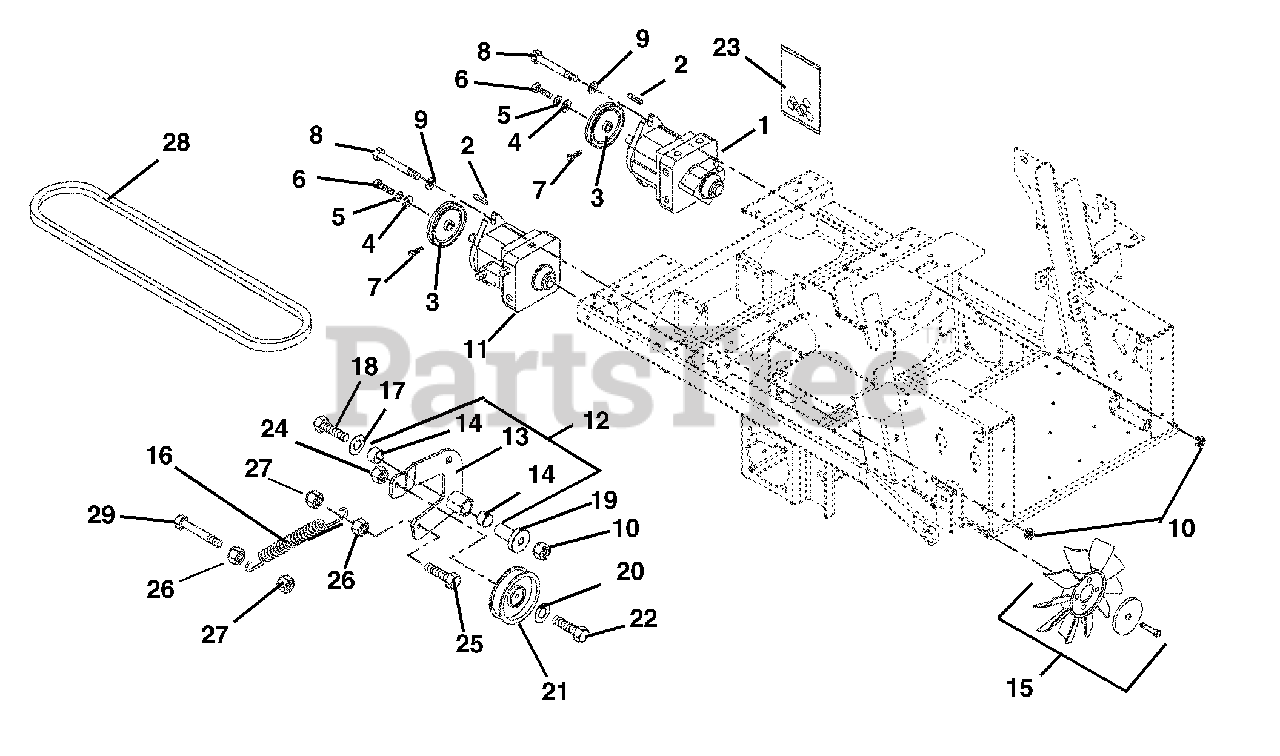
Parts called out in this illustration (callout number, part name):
1	Hydrostat BDP with Auxiliary
2	Key, Square 5 x 5 x 30mm Plain
3	Sheave, Poly-V .671 x 4.125
4	Washer-Flat-Steel .25 x 1.0 x .048
5	Washer-Locking .25 x .062
6	Bolt-Hex M6 x 1.0 x 12
7	Screw-Socket Head .25-20 x .50
8	Bolt-Hex .50-13 x 1.50 Grade 5
9	Washer-Flat-Steel .531 x 1.06 x .095
10	Nut-Locking-Nylon .50-13
11	Pump, Hydro
12	Assembly, Idler Arm Guard Drive
13	Weldment, Idler Arm Ground Drive
14	Bearing, 1.00 x 1.12 x .75
15	Fan Kit, Hydrogear
16	Spring-Tension .120 x .845 x 6.500
17	Washer-Flat-Steel .39 x.75 x.125
18	Bolt-Hex .50-13 x 3.50 Grade 5
19	Bearing, Pedestal Powdered Metal
20	Washer-Flat-Steel .406 x .812 x .065
21	Idler, Flat 4.00 x 1.06
22	Bolt-Hex .38-16 x 2.25 Grade 5
23	Kit-Pump Seal
24	Nut-Locking-Top-Flange .38-16
25	Bolt-Hex .31-18 x 1.25 Grade 5
26	Nut-Hex .31-18
27	Nut-Locking-Nylon .312-18
28	Belt, Poly-V 49.50
29	Bolt-Hex .31-18 x 2.50 Grade 5
